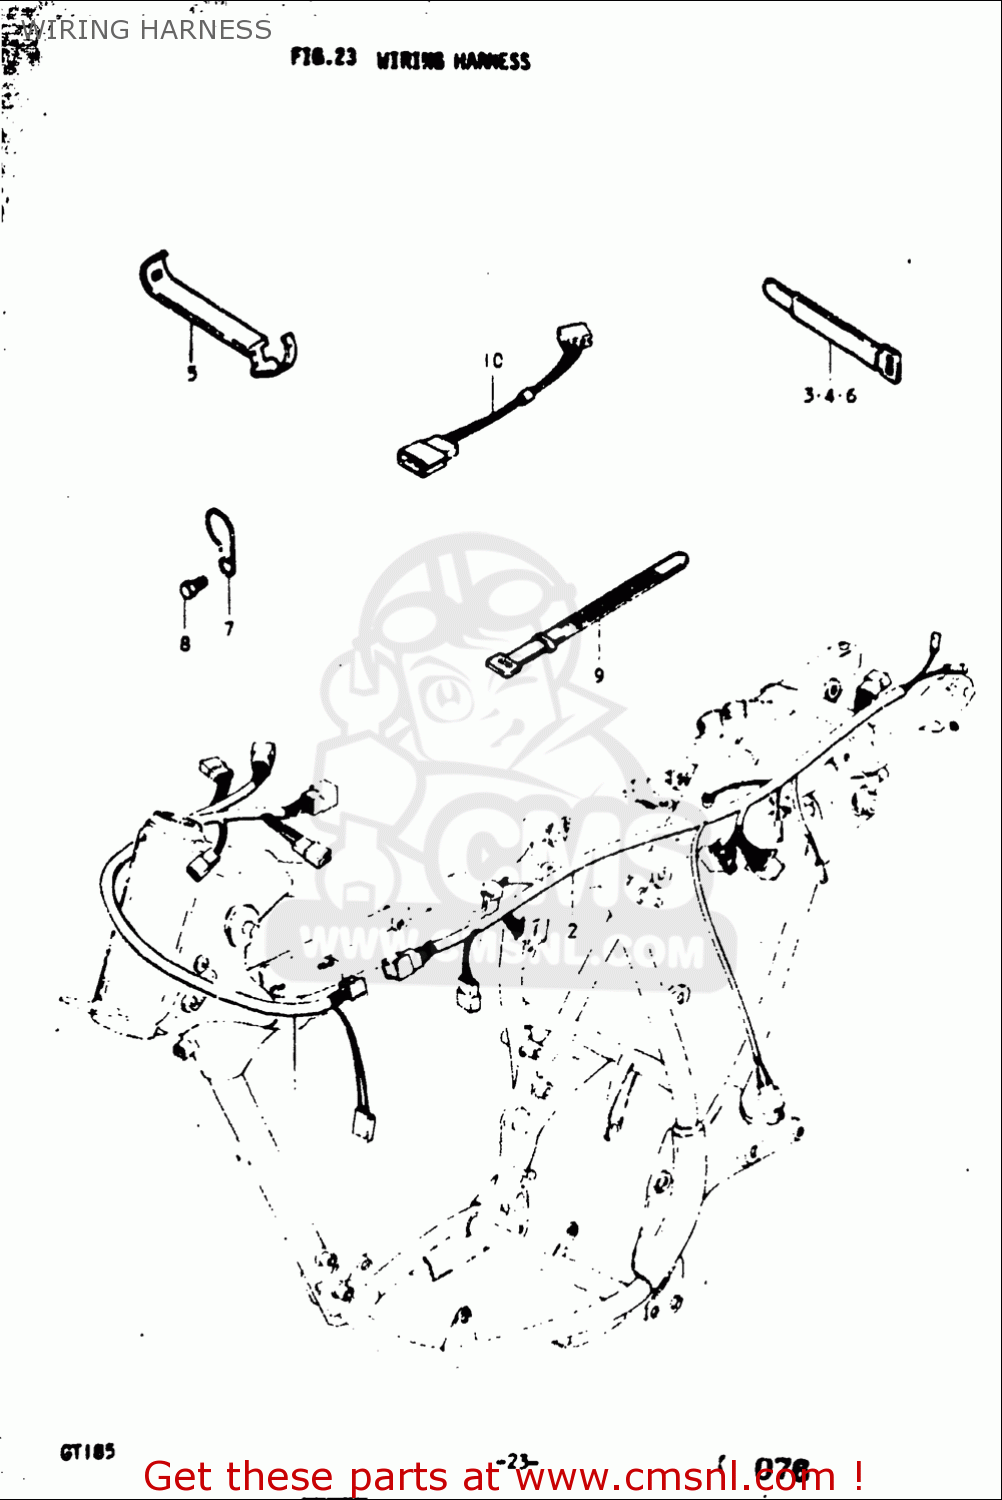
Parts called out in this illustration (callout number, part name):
1	HARNESS,WIRING
3	CLAMP
4	CLAMP
6	CLAMP
8	BOLT
9	CLAMP(L:120)
